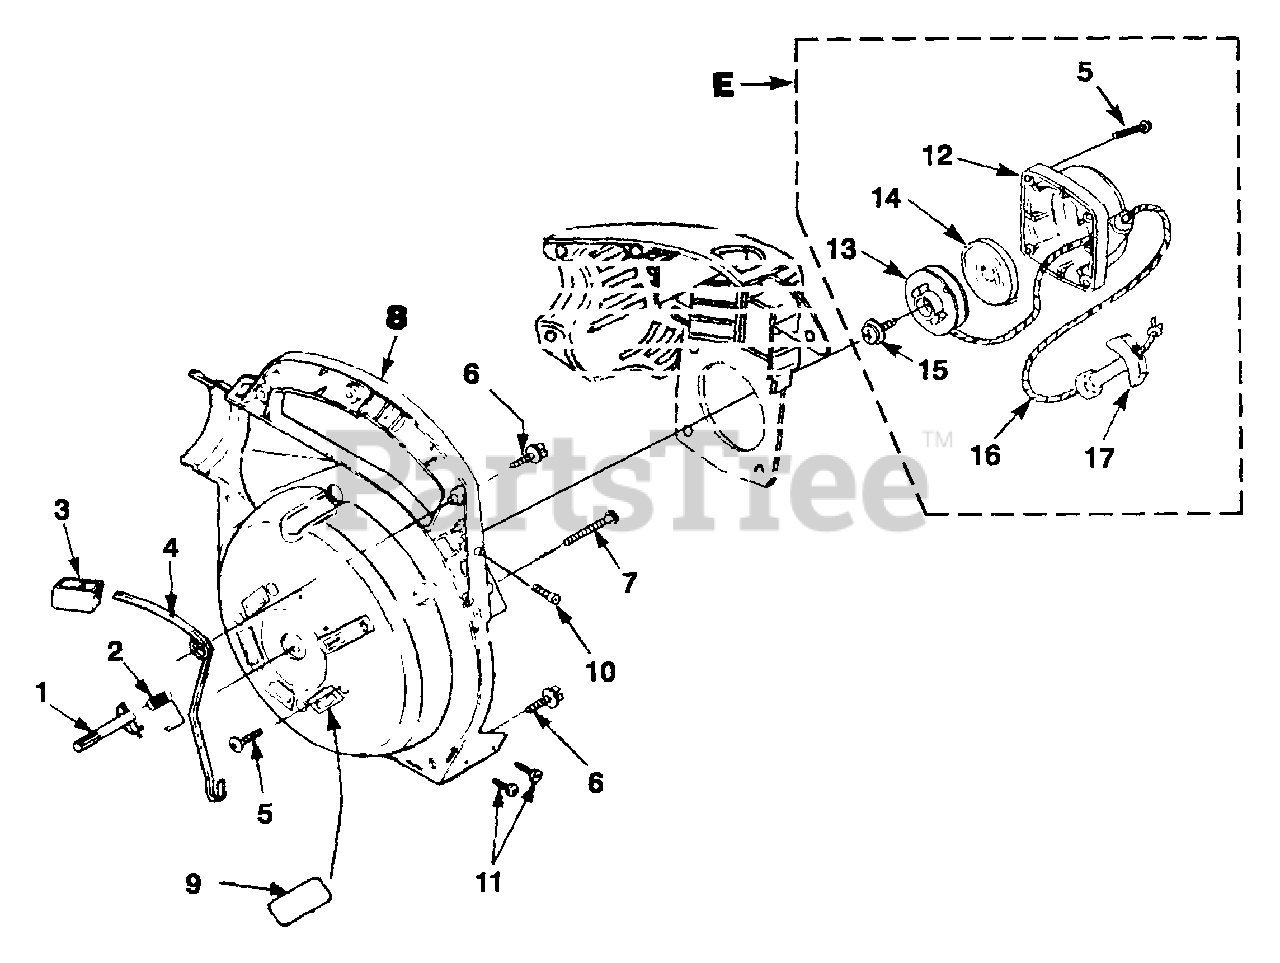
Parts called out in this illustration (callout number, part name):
1	Throttle Latch
2	Throttle Latch Spring
3	Throttle Trigger
4	Throttle Lever
5	Screw-Thread Form. (10-24 x 3/4")
6	Screw-Thread Form. (#10 x 3/4")
7	Screw-Thread Form. (#10 x 1 5/8")
8	Volute Housing, Inner
9	Sealing Kit
10	Screw-Fillister Hd. (#8-32 x 5/8")
11	Screw-Tap, Pan Hd. (#8 x 1/2")
12	Starter Housing
13	Recoil Spring
14	Starter Pulley
15	Set Screw
16	Starter Rope
17	Starter Grip
E	Starter Assembly
